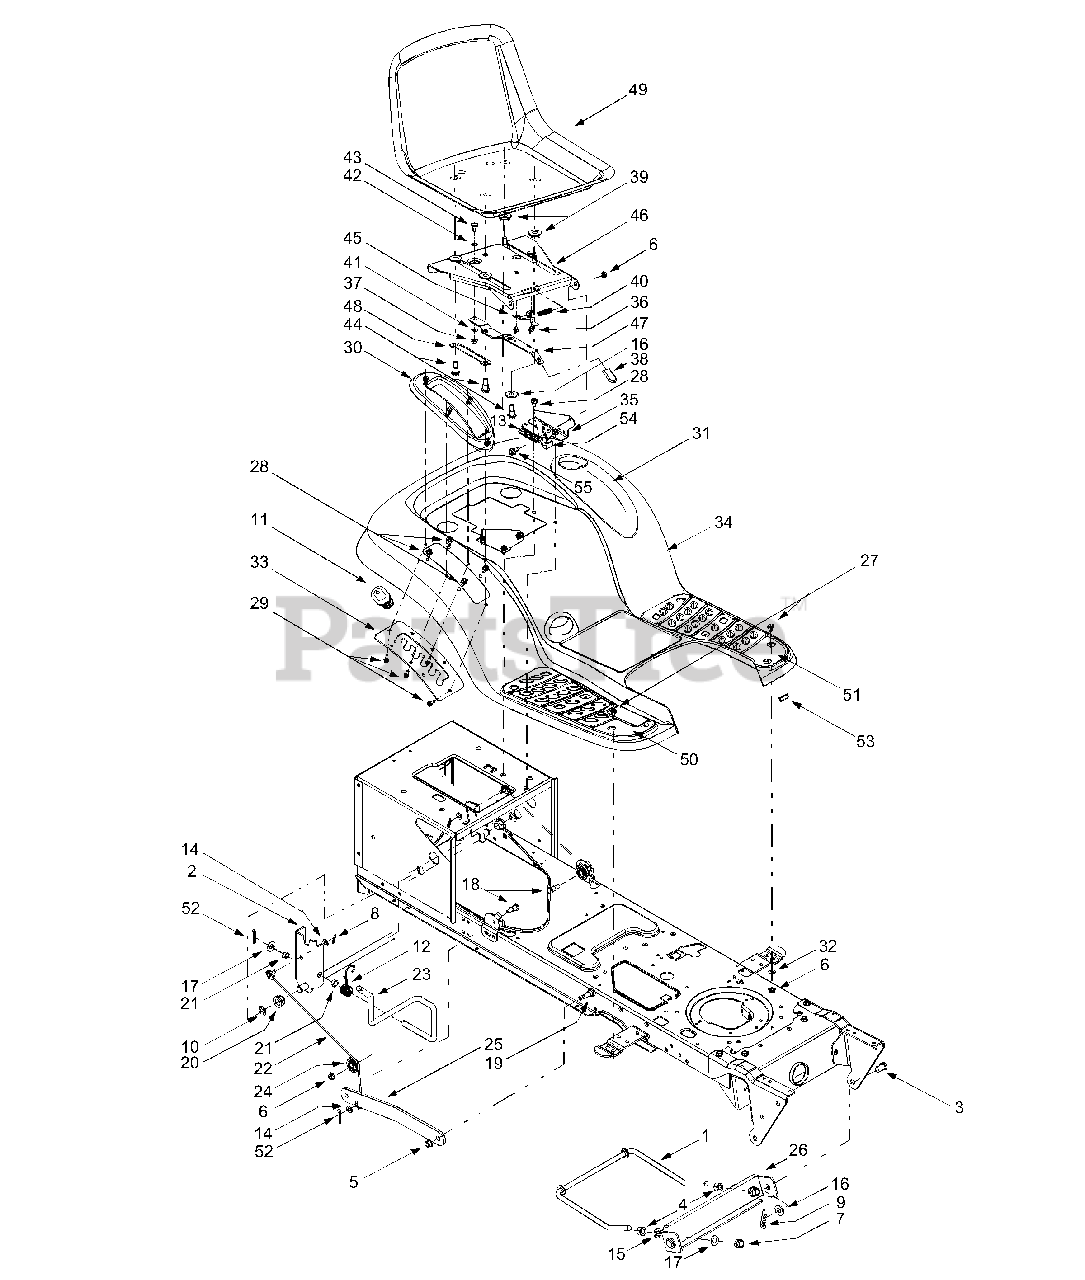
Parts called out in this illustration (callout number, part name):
1	Deck Stabilizer Rod
2	Lift Shaft Assembly
3	Clevis Pin, .5 x .78
4	Hex Nut, 1/2-13
5	Flange Lock Nut, 3/8-16
6	HEX FLANGE NUT
7	Hex Nut, 1/2-13
8	Internal Cotter Pin
9	Internal Cotter Pin
10	E-ring
11	Handle Grip
12	Torsion Spring
13	Extension Spring, .872 x 3.4
14	Flat Washer, 5/16
15	Lock Washer, 1/2
16	Flat Washer, .31 x 1.062 x .134
17	Flat Washer, .51 x 1.12 x .06
18	Hex Cap Screw, 5/16-18 x .62
19	SHOULDER SCREW .498 DIA x .340
20	Hex Flange Bearing
21	Snap Flange Bearing
22	Lift Cable, 16.16
23	Lift Handle
24	Roller Pulley
27	Carriage Bolt, 5/16 x .62
28	Self-tapping Screw, 5/16-18 x .625
29	Self-tapping Screw, 1/4-15 x .75
30	Lift Lever Cover
31	Cover w/ Cup Holder
32	Flat Washer, .349 x 1.0 x .063
33	Lift Adjustment Bracket
36	Screw, #10-16 x .375
37	Hex Flange Lock Nut, 1/4-20
38	Seat Adjuster Grip
39	Spacer
40	Compression Spring, .41 x 1.5
41	Spring Washer, .265 x .562 x .025
42	Flat Washer, .344 x .62 x .03
43	Shoulder Screw, .340 x .285,1/4-20
44	Shoulder Screw, .50 x .50, 3/8-16
45	Seat Stop
48	Seat Adjustment Selector
49	Medium Back Seat, Black
50	RH Foot Pad
51	LH Foot Pad
51	Foot Pad Clips
52	Cotter Pin
53	Trim Strip
54	LH Seat Lift Bracket
54	BRACKET-SEAT LIFT
55	Shoulder Screw, .437 x .162
